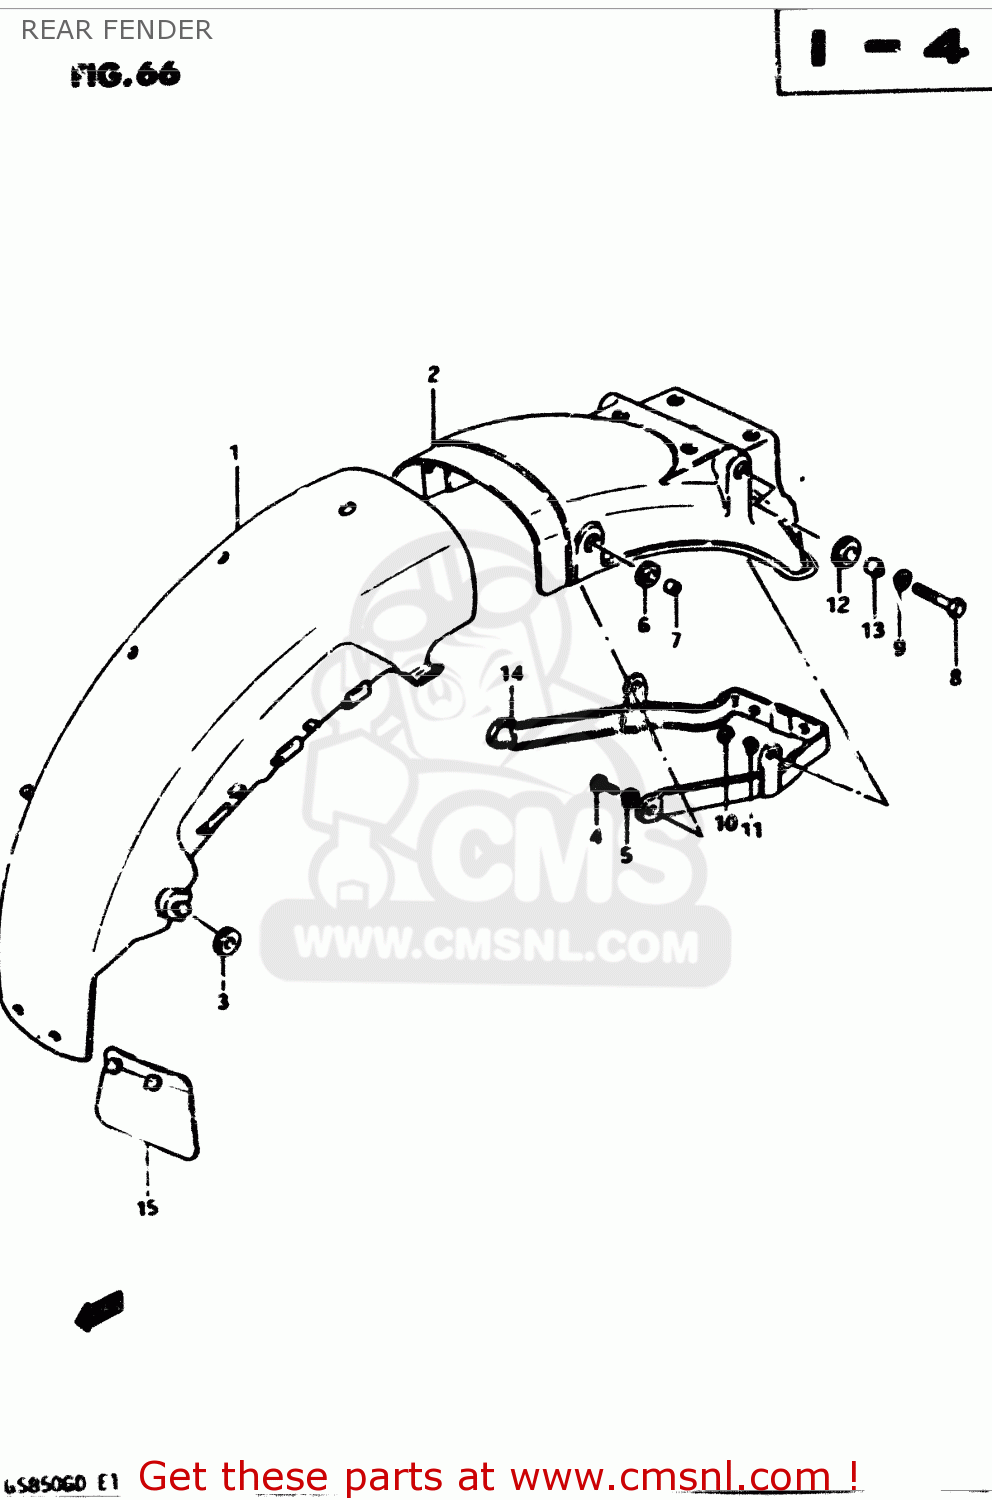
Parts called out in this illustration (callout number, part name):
1	FENDER,REAR
2	FENDER,REAR
3	CUSHION
4	BOLT, UPPER
5	LOCK WASHER
6	CUSHION
7	SPACER(6.1X9X7.5)
8	BOLT (8X30)
9	WASHER
10	NUT
11	LOCK WASHER
12	CUSHION
13	SPACER (8.2X12X7.5)
14	REINFORCEMENT,REAR FENDER
15	GUIDE,RR FENDER MUD
